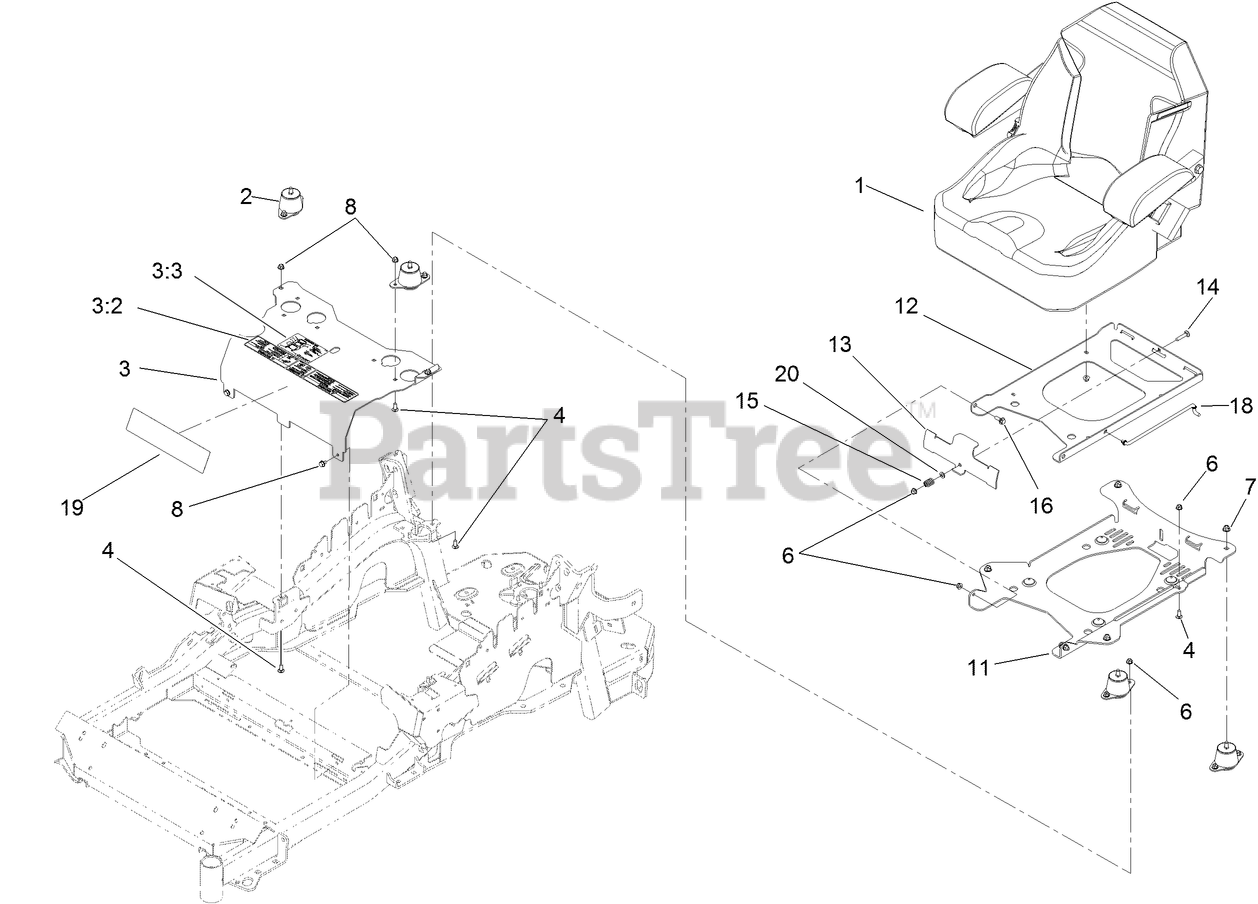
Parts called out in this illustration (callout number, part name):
1	SEAT-STANDARD
2	ISOLATOR-SEAT
3	MOUNT-SEAT
3:2	DECAL-CONSOLE
3:3	DECAL-SERVICE AID
4	SCREW-CARR
6	NUT-HF, NI
7	NUT-HF, NI
8	SCREW
11	PLATE-TILT, SEAT SUPPORT
12	PLATE-FRAME, SEAT
13	PLATE-LATCH, SEAT
14	BOLT-CARR
15	SPRING-COMPRESSION
16	SCREW-SHOULDER
18	ROD-PROP
20	WASHER-PLAIN
